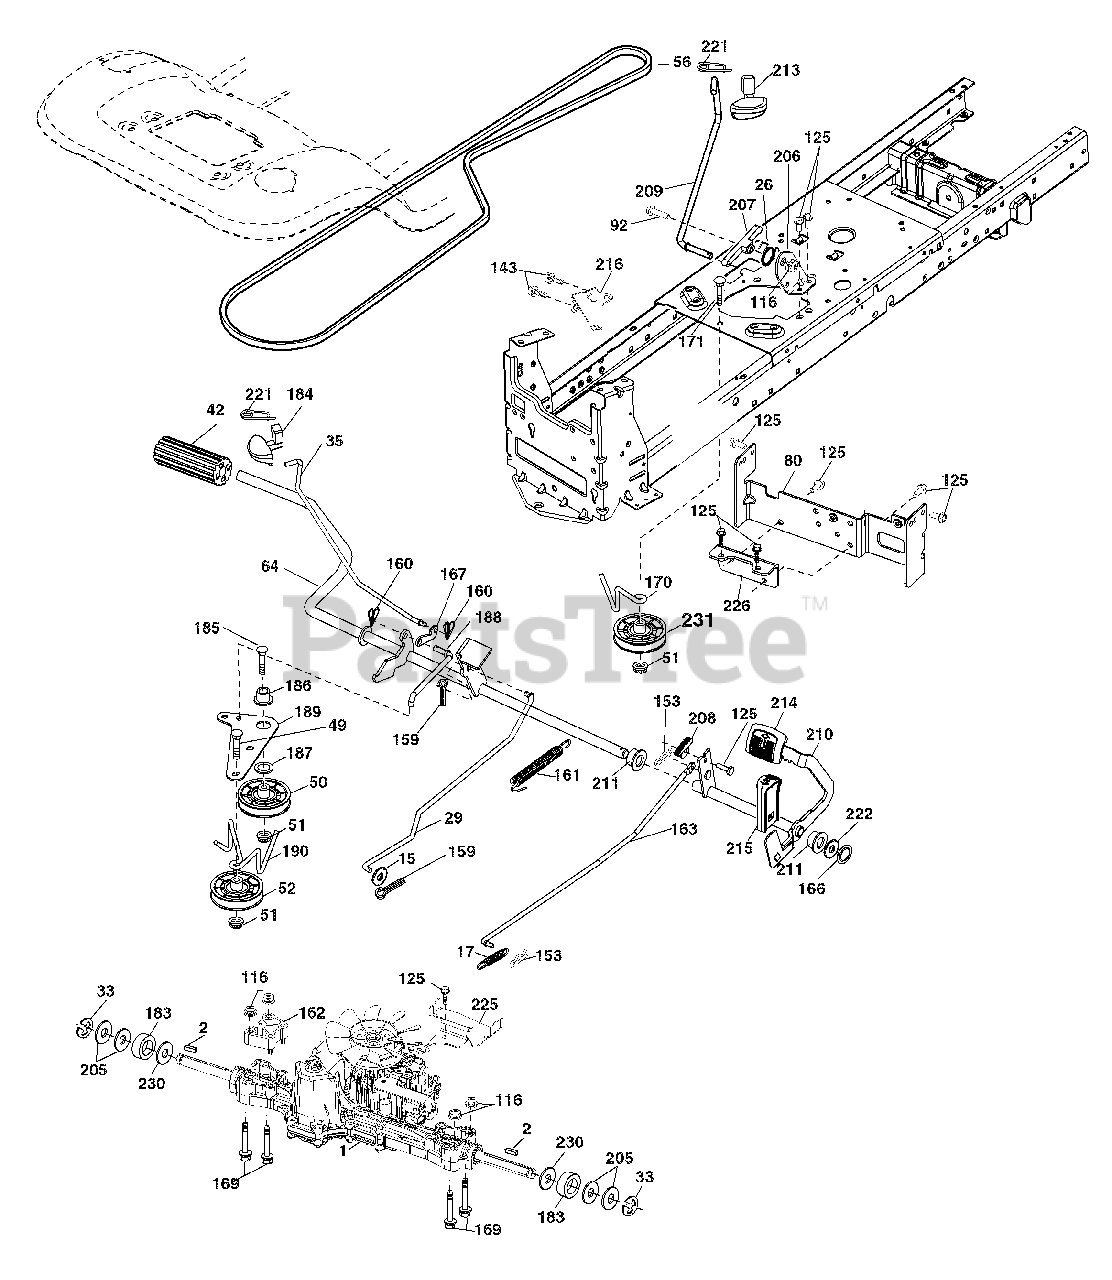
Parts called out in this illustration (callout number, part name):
1	Transaxle, TUFFTORQ K46
2	Key Square
15	Washer 13/32 x 13/16 x 16 Ga.
17	Spring, Brake
26	Spring Return Cruise
29	Rod, Brake
35	Rod, Brake, Park
42	Cover, Foot Pedal
50	Pulley Idler Flat
51	Lock Nut 3/8-16
52	Idler V-Groove 910" Offset
56	V-Belt, Drive
64	Shaft Asm. Pedal Brake Control
80	Strap Torque
92	Bolt Fin Hex 5/16-18 unc x 1.25
116	Nut Lock Hex Flange 5/16-18
125	Screw 5/16-18 x 3/4
143	Screw 5/16-18 x 1/2
153	Retainer Spring
159	Pin Cotter 1/8 x 3/4
160	Retainer Clip
161	Spring, Return, Clutch
162	Spacer Transaxle
163	Rod Pedal Control
166	Nut Push
167	Latch Brake Parking
169	Bolt Hex 5/16-18 x 3.75
170	Keeper Belt Centerspan
183	Spacer Axle
184	Handle Parking Brake
186	Spacer Retainer
187	Washer
188	Link Clutch Ground Drive
189	Bellcrank Ground Drive
190	Keeper Bellcrank Ground Drive
205	Washer 25/32 x 1-5/8 16 Ga.
206	Bracket Mount Latch Cruise
207	Latch Control Cruise
208	Gear Sector Control Cruise
209	Rod Control Cruise
210	Rockr Asm. Pedal Control
211	Bearing Nylon
213	Knob control Cruise
214	Pad Pedal Forward
215	Pad Pedal Reverse
216	Bracket Pulley Idler
221	Retainer Spring Clip
222	Washer 21/32 x 1-1/4 10 Ga.
225	Keeper Belt Transaxle
226	Bracket Mount Torque
230	Washer Hardened
231	Idler V-Groove 1.688" OFFSET
